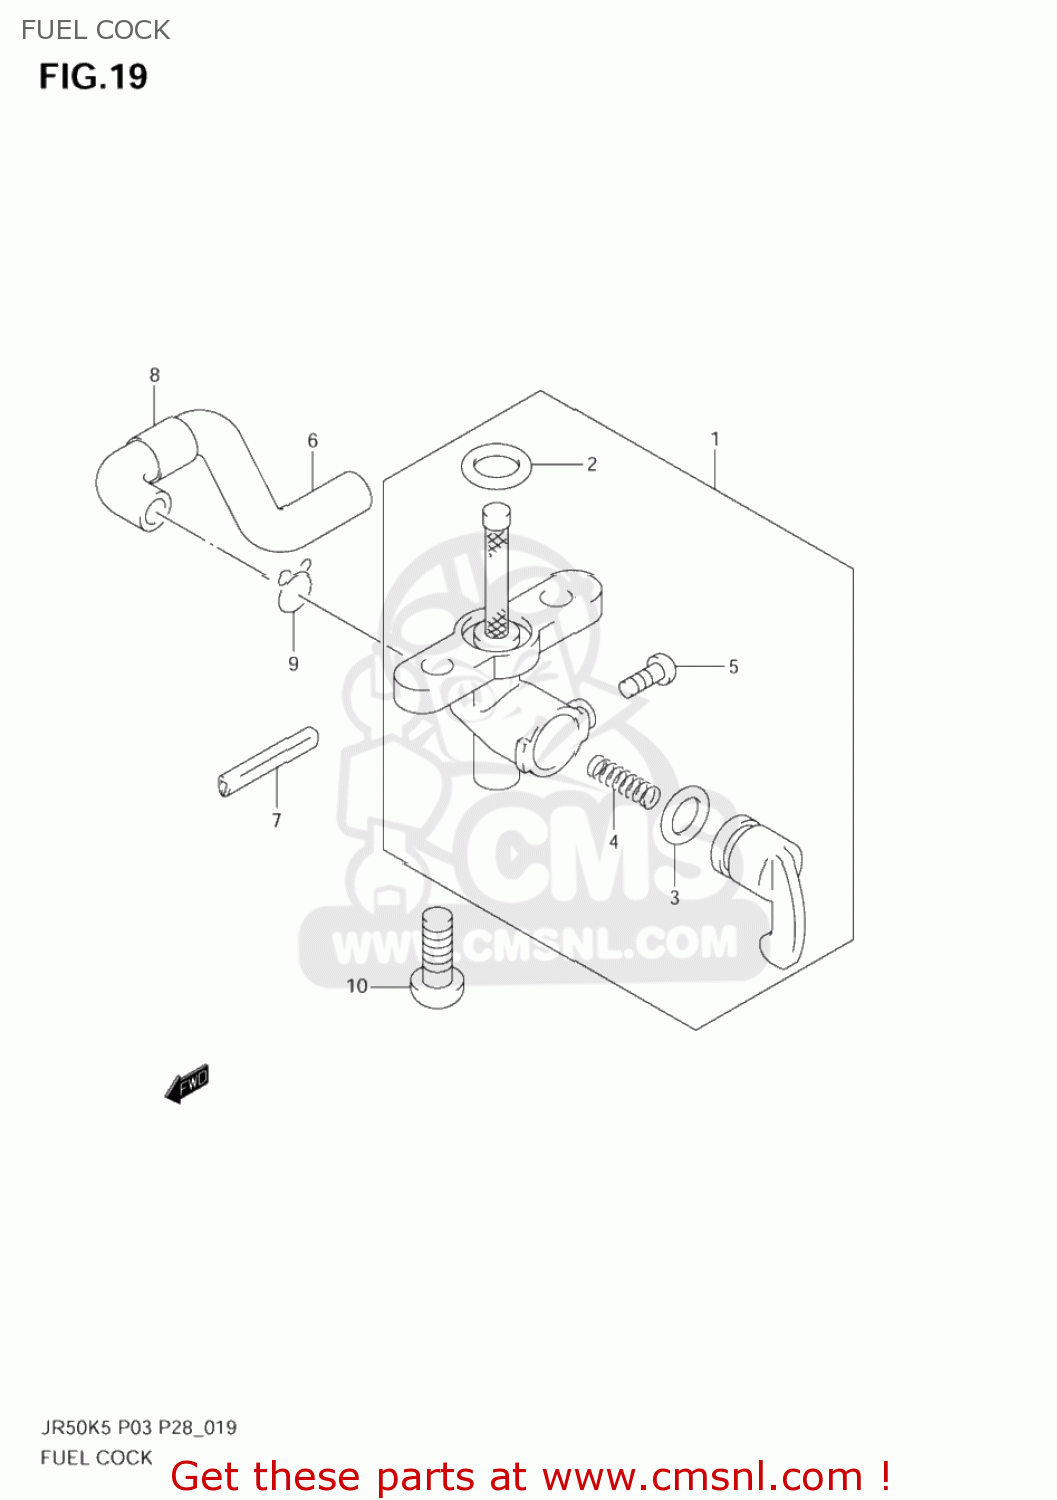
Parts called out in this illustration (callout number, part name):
1	COCK ASSY,FUEL
2	O RING
3	O RING,LEVER
4	SPRING
5	SCREW
6	HOSE,FUEL
7	PROTECTOR,NO.1
8	PROTECTOR(14.5X15.5X600)
9	CLIP
10	BOLT
